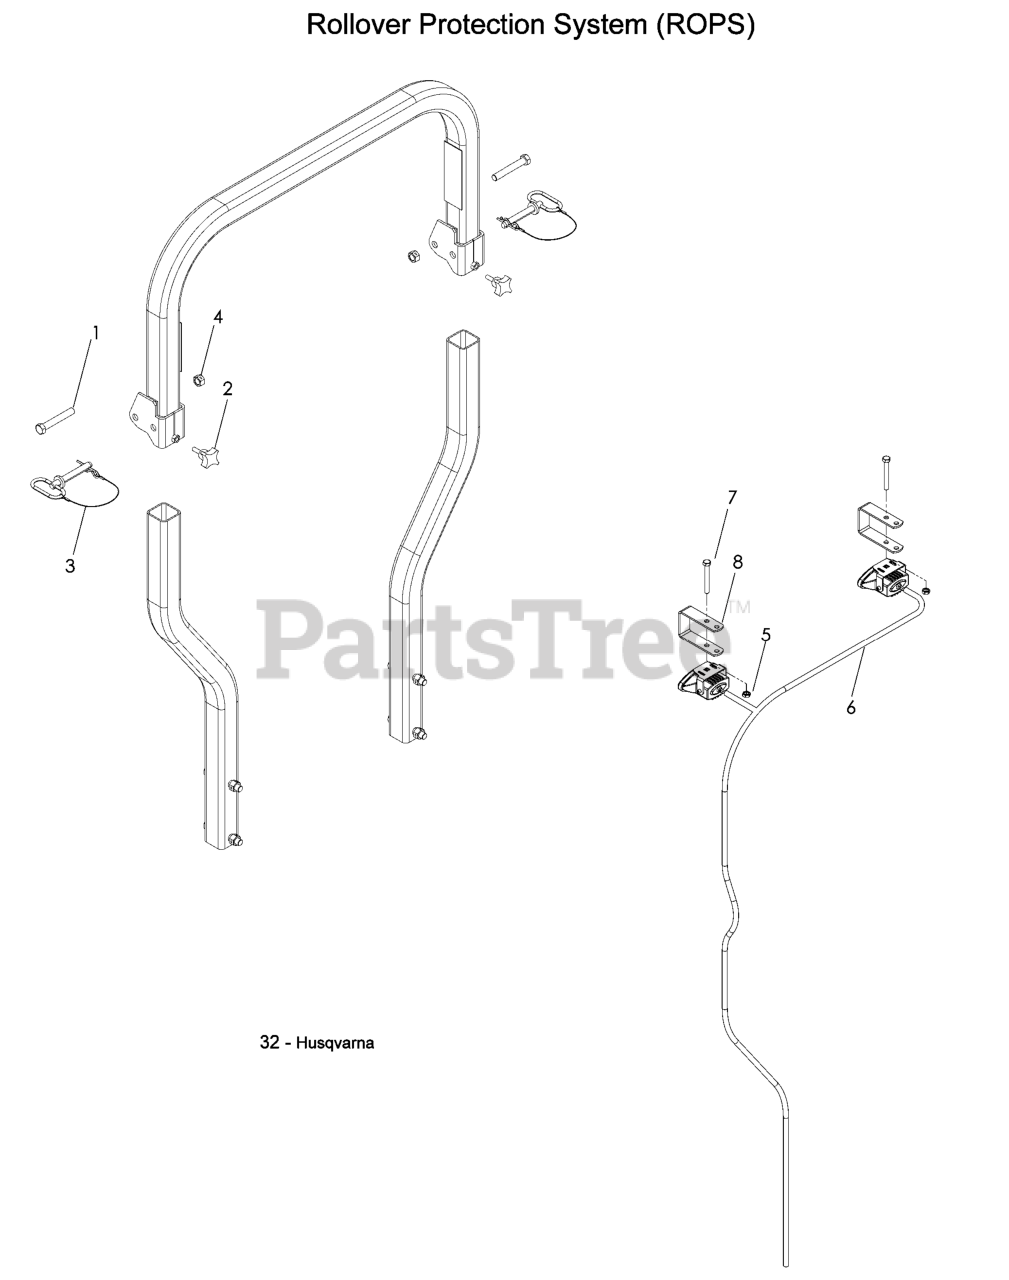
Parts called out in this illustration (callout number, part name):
1	HCS 1/2C X 3 1/4
2	KNOB W/STUD 3/8-16 X 1.5
3	PIN, 1/2" W/LANYARD
4	NUT 1/2-13 HEX CNTRLK GR 5 ZD
5	NUT 5/16-18 HEX JAM ZD
6	LIGHT HARNESS
7	BOLT 5/16C X 2 1/2
8	LIGHT MOUNTING BRACKET
